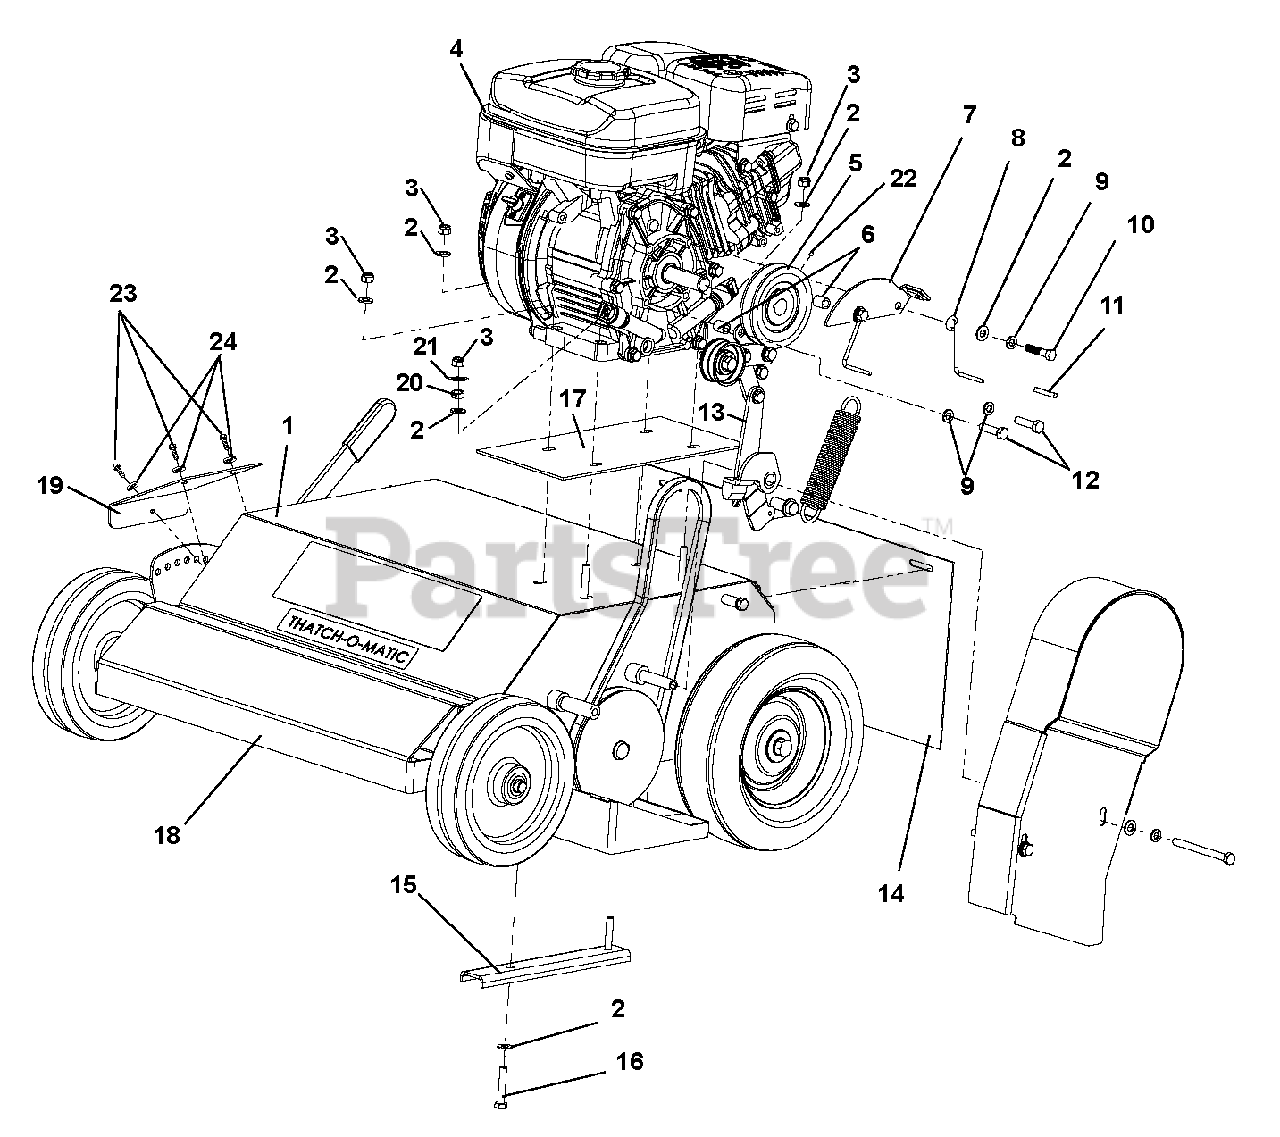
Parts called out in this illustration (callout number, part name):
1	Housing Weldment w/ Decals
2	Washer, Flat-Steel .344 x .688 x .065
3	Nut, Locking-Nylon 5/16-18
4	Engine, Subaru 6HP SP170 (Carb)
5	Pulley, 2275-3/4" Bore (995862)(Used with spring tine reel)
7	Weld-Bracket
8	Belt Finger
9	Washer, Locking .31 x .078 Regular
10	Bolt, Hex Head 5/16-24 x 1.5
11	3/16 Key 1 1/4"
12	Bolt HH 5/16-24 x 1.25
13	Clutch Pulley Assembly
14	Drag Strip
15	Stiffener
16	Bolt, Hex .31-18 x 1.75
17	Mounting Plate
18	Front Bumper Welment
19	Guard, Right Hand (995863 Thatch-O-Matic with Flail Assembly)
20	Nut, Locking-Center-Jam .31-18
21	Washer, Lock Internal .31
22	Screw, Set .31-18 x .38 Socket Head
23	Bolt, Hex .25-20 x .75 Grade 5
24	Washer, Locking .25 x .062 Regular
